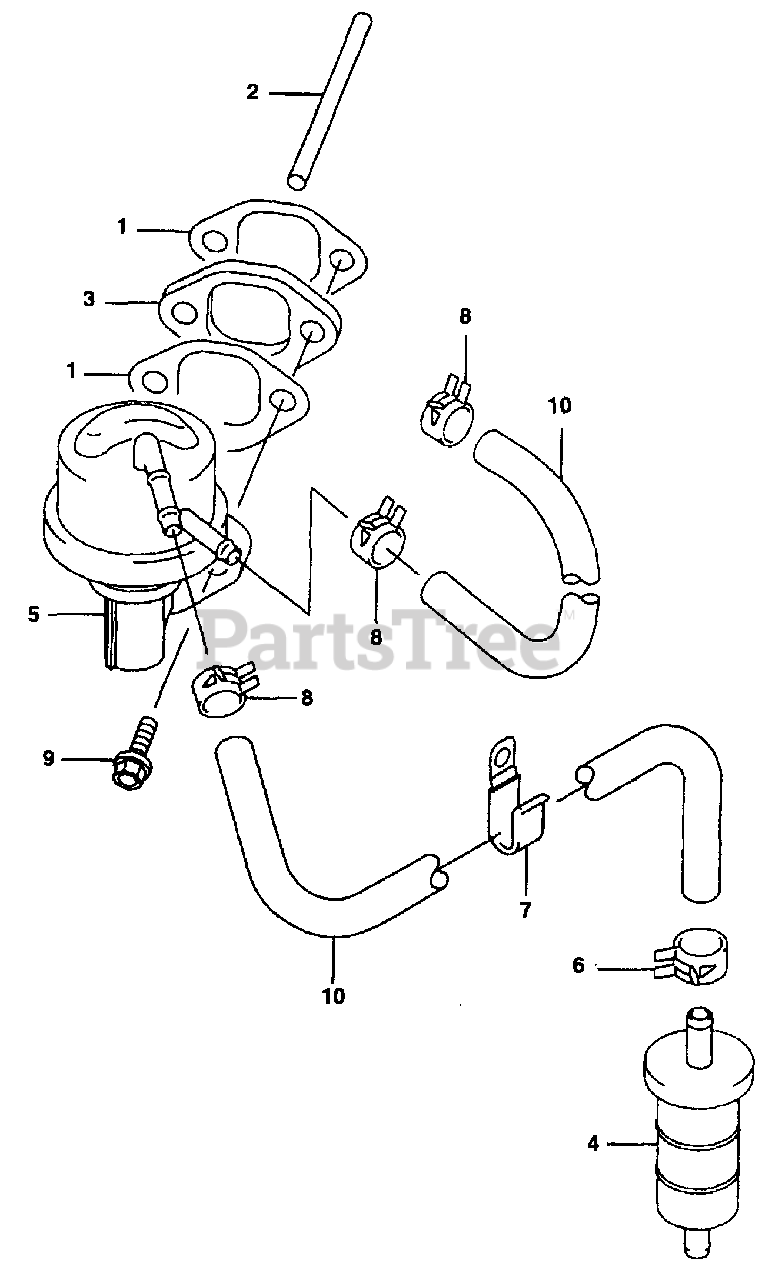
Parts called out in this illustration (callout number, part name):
1	Fuel Pump Gasket
4	Fuel Filter
5	Fuel Pump
9	Flanged Bolt
